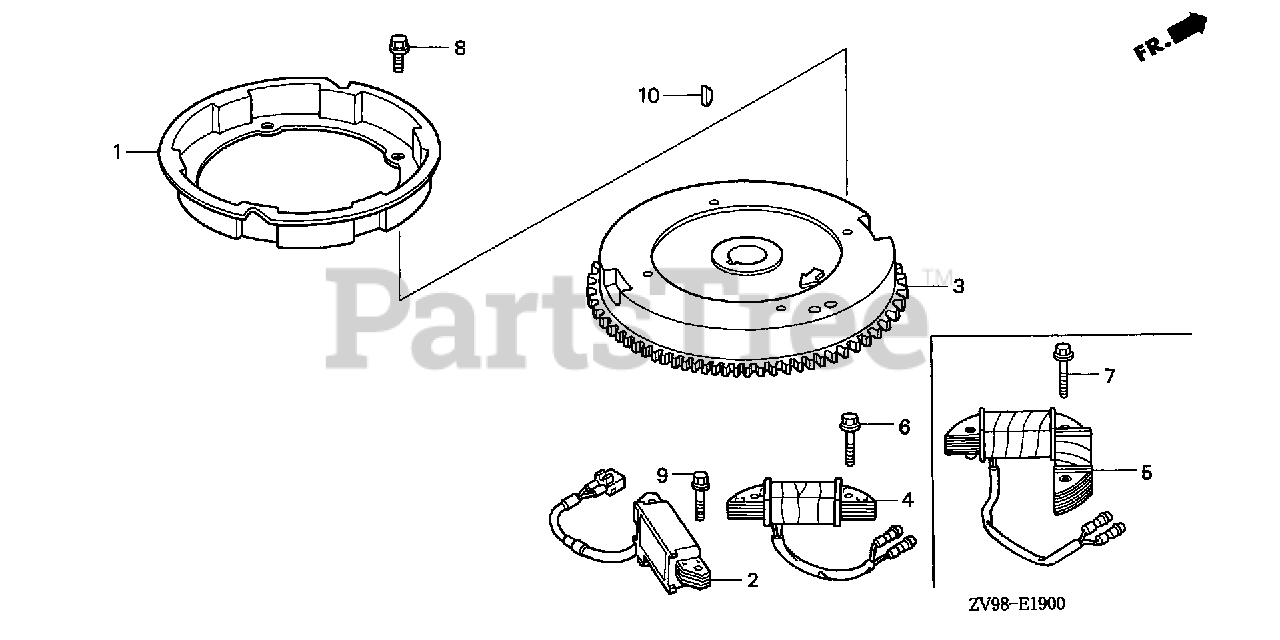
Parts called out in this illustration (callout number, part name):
1	PULLEY, STARTER
2	COIL ASSY., EXCITER
3	FLYWHEEL *TBLACK* (BLACK)
4	COIL ASSY., CHARGE (12V-6A)
5	COIL ASSY., CHARGE (12V-10A)
6	BOLT, FLANGE (6X35)
7	BOLT, FLANGE (6X35)
8	BOLT, FLANGE (6X12)
9	BOLT, FLANGE (6X25)
10	KEY, SPECIAL (16X15)
